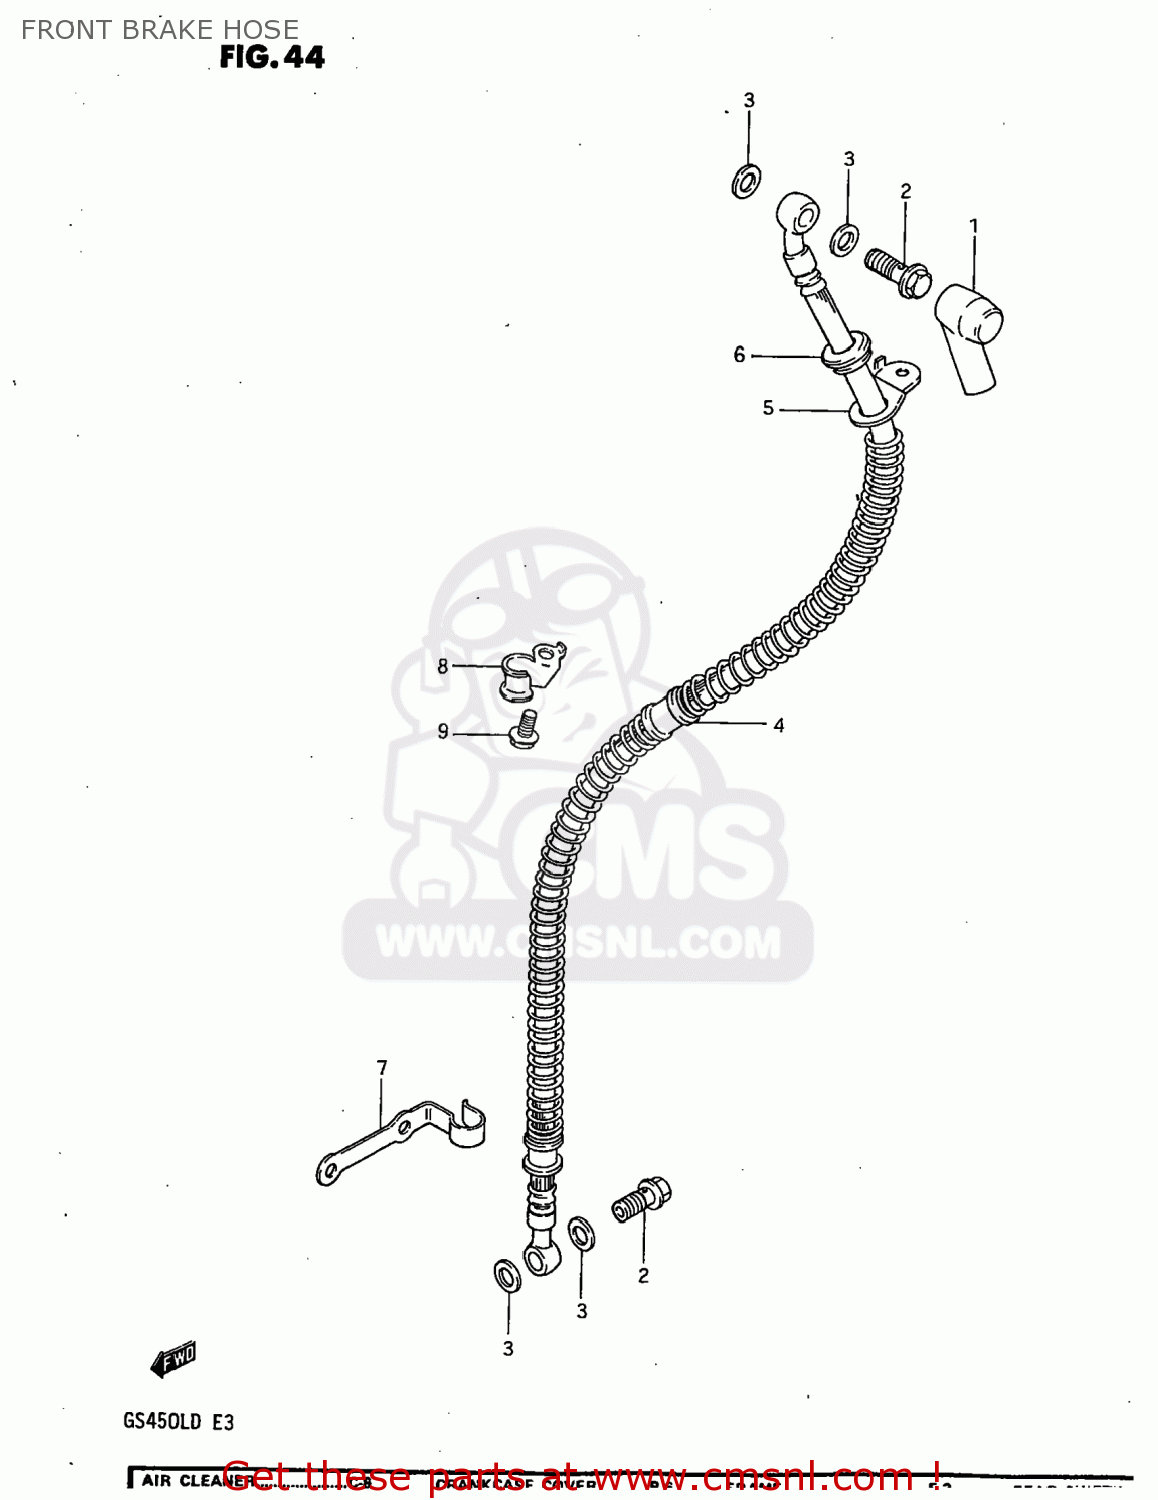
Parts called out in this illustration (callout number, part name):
1	BOOT,MASTER CYLINDER
2	BOLT,UNION
3	WASHER
4	HOSE,FRONT BRAKE
5	GUIDE,BRAKE HOSE
6	GROMMET
7	GUIDE,BRAKE HOSE NO.2
8	GUIDE,BRAKE HOSE NO.3
9	BOLT
